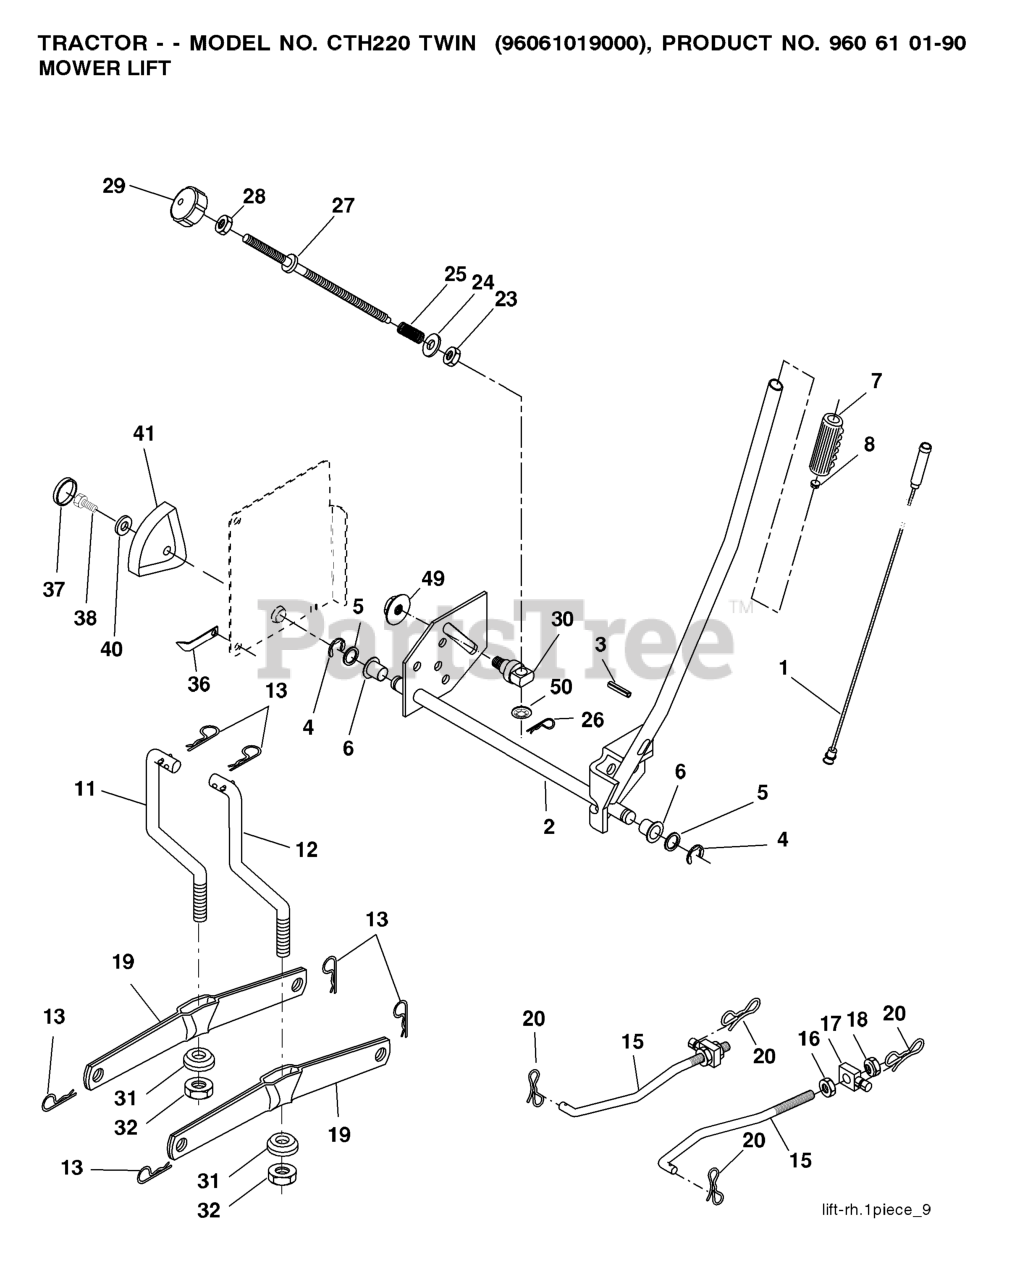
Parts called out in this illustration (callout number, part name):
2	SHAFT.ASM.LIFT.YT
3	PIN.GROOVE.5/16
4	RETAINING RING LT
6	BEARING.NYLON
7	GRIP HANDLE
8	REPL BY 532 12 59-25
11	LINK
12	LINK
13	RETAINER-SPRNG RB
15	LINK.SUSPENSION.FRONT
16	NUT.HEX.JAM.1/2-13
18	NUT.LK.W/WSH.1/2.
19	ARM.REAR.SUSPENSION
20	PIN.COTTER.7/16.BOW TI.
26	RETAINER CLIP
27	ROD ADJ LIFT
28	NUT
29	KNOB INF 3/8-16
31	BEARING.PIVOT.LIFT
32	NUT CROWNLOCK 3/8-24
36	POINTER, HEIGHT INDICATOR(2 2)
38	SCREW 5/16-18X1
41	HEIGHT INDICATOR
49	NUT
50	NUT PUSH M
